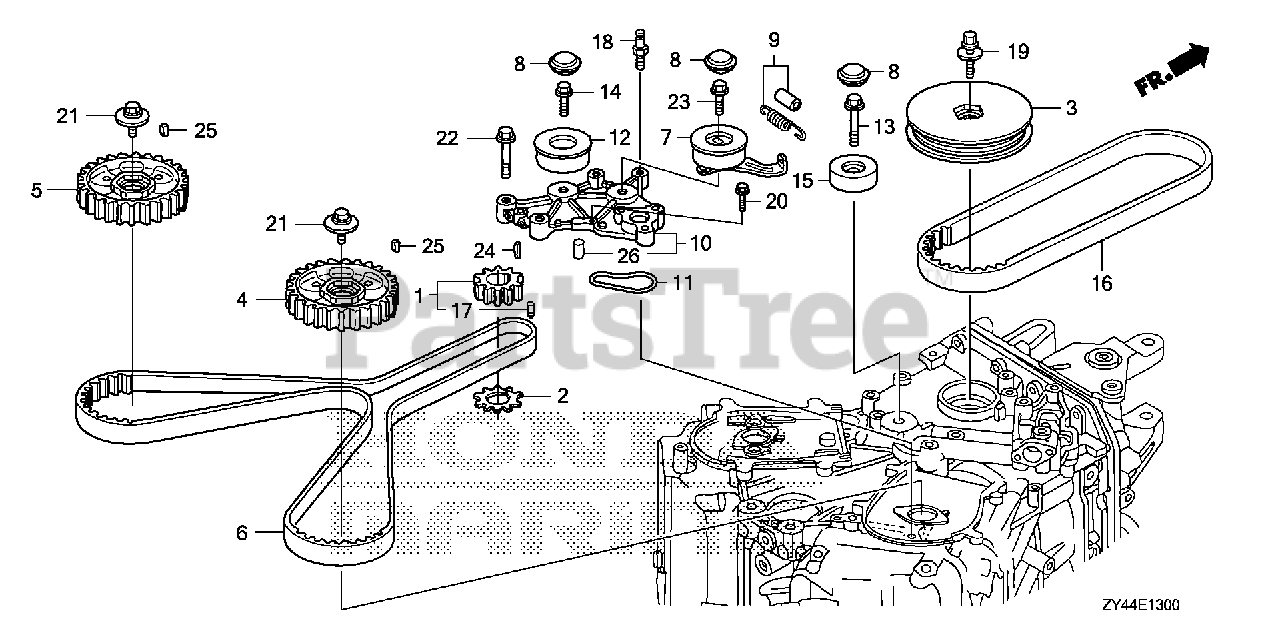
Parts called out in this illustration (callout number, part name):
1	PULLEY, TIMING BELT DRIVE
2	PLATE, TIMING BELT GUIDE
3	PULLEY, CRANKSHAFT
4	PULLEY, R. TIMING BELT DRIVEN
5	PULLEY, L. TIMING BELT DRIVEN
6	BELT, TIMING (197YU26 GB-323)
7	TENSIONER, TIMING BELT
8	CAP, TIMING BELT TENSIONER
9	SPRING, TIMING BELT ADJUSTING
10	BASE, TIMING BELT TENSIONER *NH8* (DARK GRAY)
11	O-RING, TIMING BELT TENSIONER BASE
12	IDLER, TIMING BELT (KOYO SEIKO)
13	BOLT, IDLER
14	BOLT, TIMING BELT IDLER A
15	IDLER B, TIMING BELT
16	BELT, ALTERNATOR (6PK745 M-180)
17	PIN, VERTICAL SHAFT
18	BOLT, TIMING BELT ADJUSTING SPRING
19	BOLT-WASHER (16X49)
20	BOLT, FLANGE (6X22)
21	BOLT-WASHER (12X35)
22	BOLT, FLANGE (10X40)
23	BOLT, FLANGE (10X43)
24	KEY (4.5X24)
25	KEY, SPECIAL
26	PIN, DOWEL (6X10)
